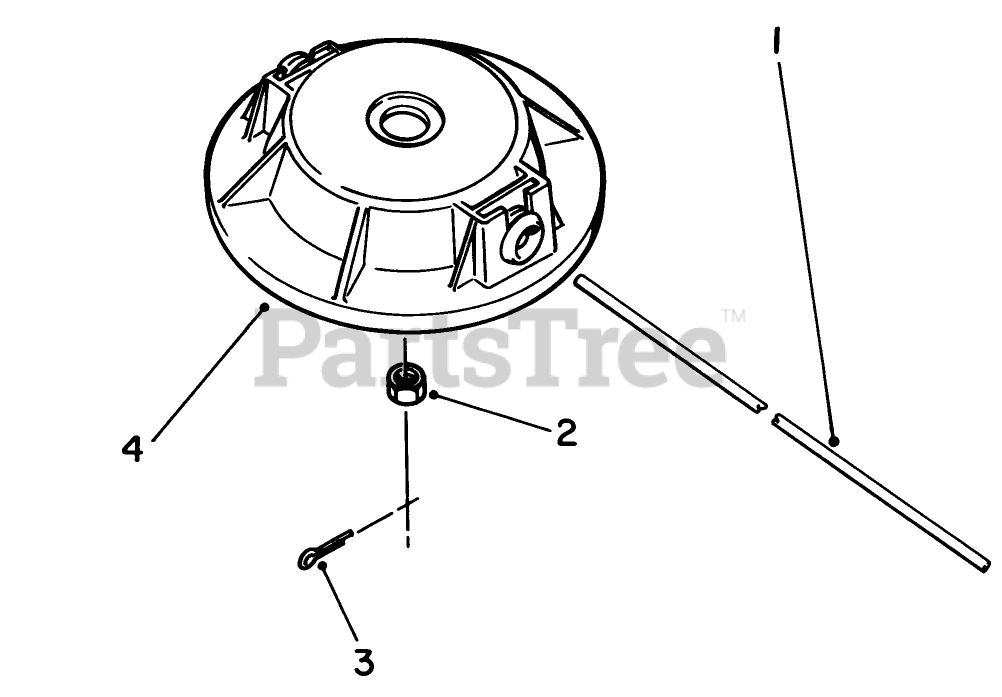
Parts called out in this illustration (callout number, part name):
1	LINE PACK (100)
3	PIN-COTTER
4	CUTTER HEAD-PLASTIC
